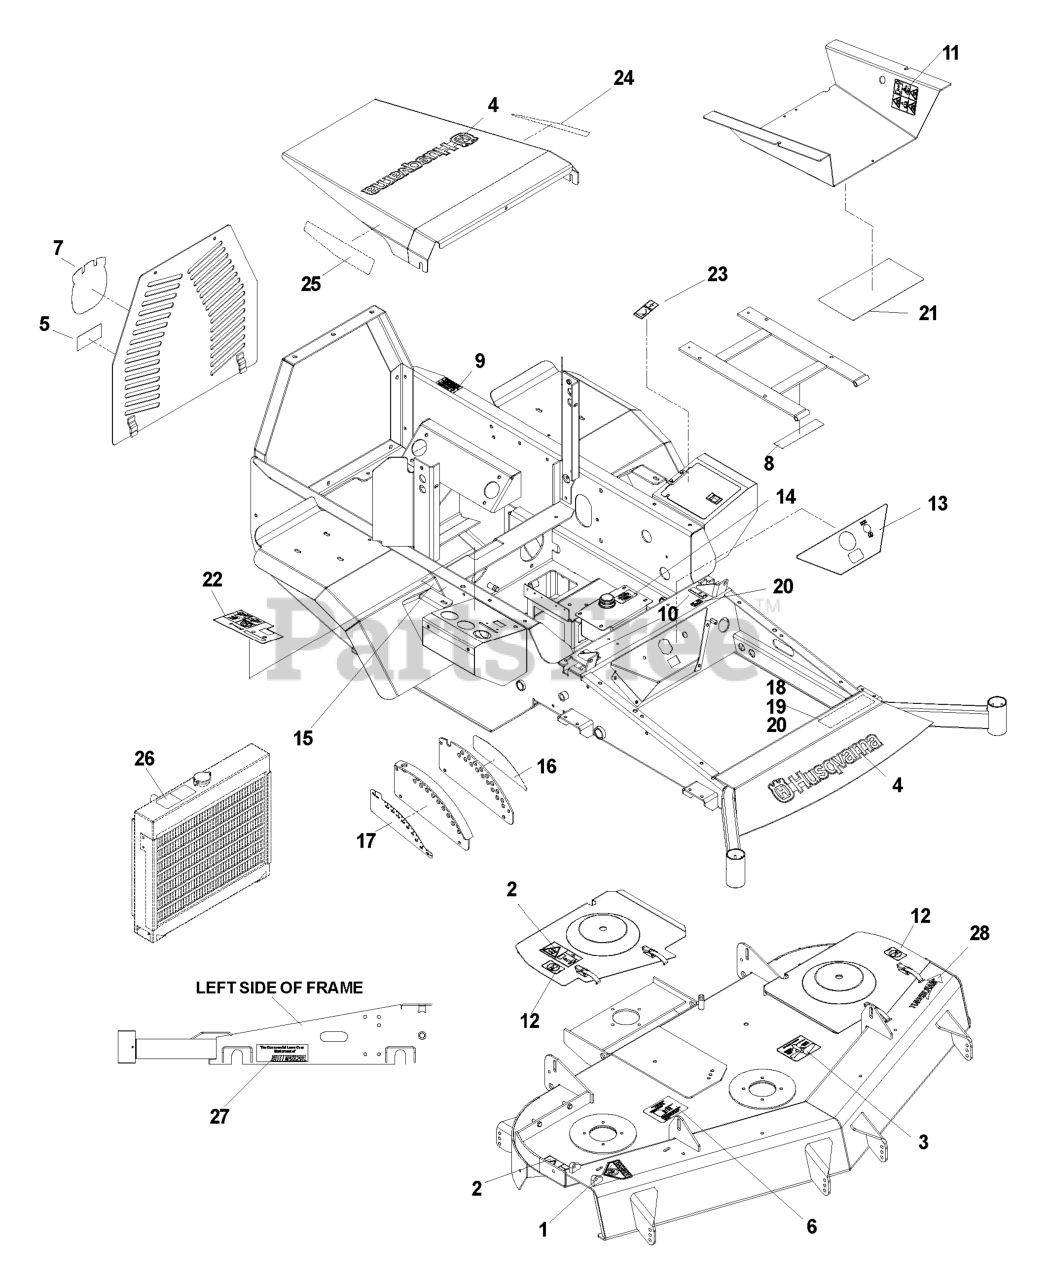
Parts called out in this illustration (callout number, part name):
1	DECAL, CPSC
2	DECAL, EURO SEVERING
3	DECAL, BELT ROUTING
4	DECAL, HUSQ 15" BLUE
5	DECAL, BELT DRIVE
6	DECAL, ANTI SCALP
7	DECAL, CROWN H BLUE
8	EURO DECAL-BATTERY WARNIN6
9	DECAL, PROP. 65
10	DECAL, MOTION CONTROL
11	DECAL, WARNING
12	DECAL, NO STEP
13	DECAL, CONSOLE
14	DECAL, MOBIL 1
15	FUEL VALVE DECAL
16	DECAL, HEIGHT
17	DECAL, HEIGHT
18	DECAL, BZ6127
19	DECAL, BZ7234
20	DECAL, F.S.T.
21	DECAL, SERVICE
22	DECAL, RT CONSOLE
23	DECAL, 12V D.C.
24	DECAL, 34 TURBO LH
24	DECAL, 27HP DIESEL LEFT
25	DECAL, 34 TURBO RH
25	DECAL, 27HP DIESEL - RIGHT
26	DECAL, HOT
27	DECAL, NASCAR
28	DECAL, TUNNEL RAM 8"
